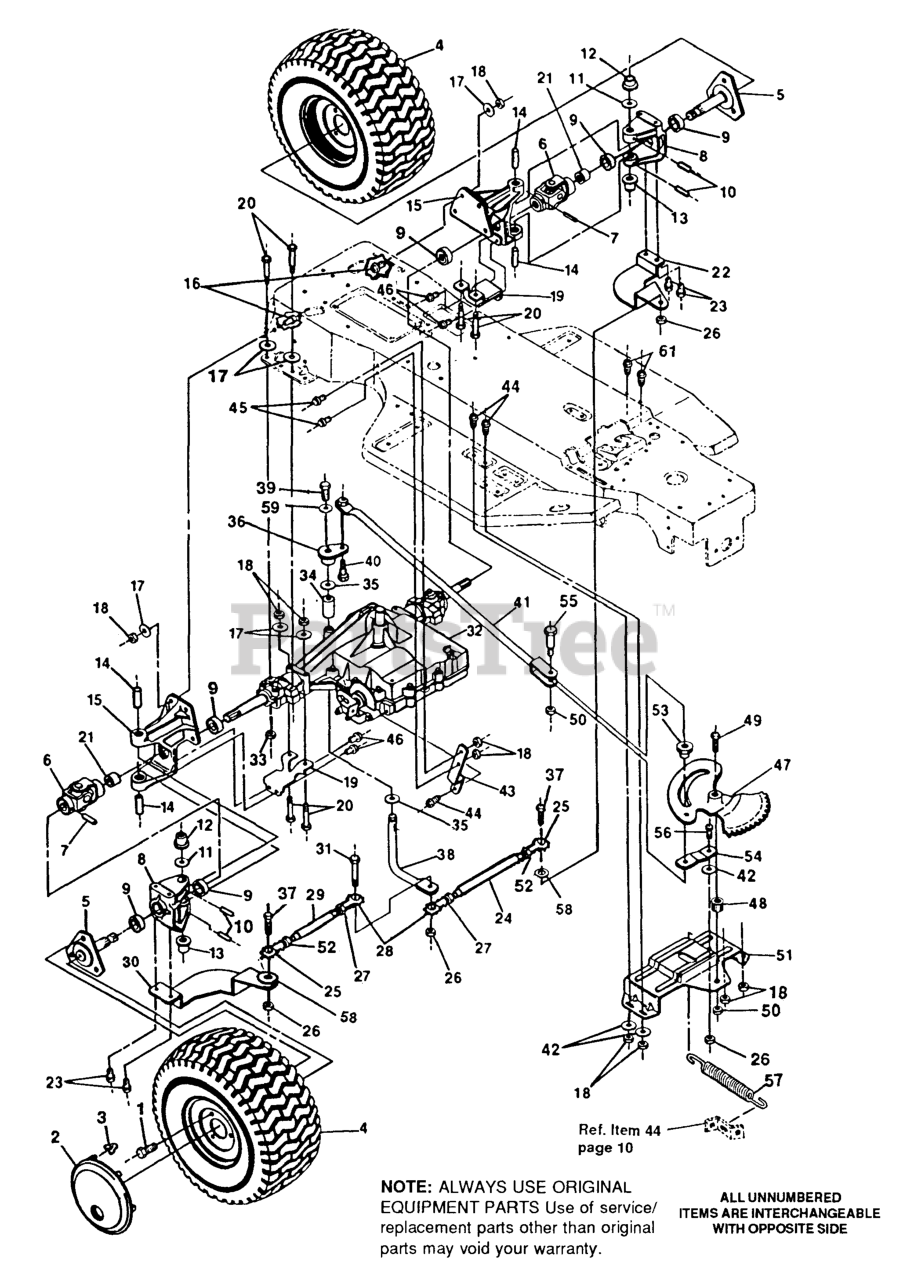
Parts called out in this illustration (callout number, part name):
1	Screw, Hx Hd, 1/2-20 x 1/2 In.
2	Hubcap, 8 In.
3	Clip, Hubcap
4	Wheel & Tire Assembly, Rear
4	Valve Stem
5	Hub Assembly
6	U-Joint Assembly
7	Pin, Grooved, 1/4 x 1-1/2 In.
8	Bracket, Steering Pivot, Outer
9	Bearing
10	Pin, Spring, 1/4 x 1-1/2 In.
11	Washer, Flat
12	Bushing, Shouldered
13	Bushing, Shouldered
14	Pin, Steering Hinge
15	Bracket, Steering Pivot, Inner
16	Screw, Hx Hd, 5/16-18 x 1 In.
17	Washer, Flat, 11/32 In.
18	Nut, Hx, Ctrlk 5/16-18 Thd.
19	Bracket, Transaxle Mounting
20	Screw, Hx Hd, 5/16-18 x 2-1/4 In.
22	Arm, Rear Wheel Steer, L. H.
23	Screw, Self-Tap, 3/8-16 x 3/4 In.
24	Tie Rod, L.H.
25	Tie Rod End, L.H.
26	Nut, Hex, Ctrlk, 3/8-24 Thd.
27	Nut, Hex, Jam, 3/8-24 Thd.
29	Tie Rod End, R.H.
30	Arm, Rear Wheel Steer, R.H.
31	Screw, Hx Hd, 3/8-24 x 1-3/4 In.
32	Contact nearest dealer
33	Nut, Hx, Wd Fl, Lk 5/16-18 Thd.
35	Washer, Flat, 49/64 In.
36	Steering Pivot
37	Screw, Hx Hd, 3/8-24 x 1-1/4 In.
38	Shaft, Steering Pivot
39	Screw, 5/16-24 x 1 In.
40	Bolt, Shoulder, 3/8-24 Thd.
41	Rod Assembly, Rear Wheel Steer
42	Washer, Flat, 3/8 In.
43	Bracket, Transaxle Stabilizer
44	Screw, Hx Hd, Self-Tap, 5/16-18 x 3/4 In.
45	Screw, Hx Hd, 5/16-18 x 5/8 In.
46	Screw, Hx Hd, Self-Tap, 5/16-18 x 5/8 In.
47	Assembly, Sector Gear
48	Bushing, Sector Gear
49	Screw, Hx Hd, 1/2-20 x 2-3/8 In.
50	Nut, Hx, Ctrlk, 1/2-20 Thd.
51	Plate, 4-Wheel Steer Pivot
52	Nut, Jam, 3/8-24 Thd.
53	Cam Yoke Roller
54	Arm, Roller Swing
55	Shoulder Bolt, Cam Roller
56	Shoulder Bolt, Cam Follower Arm Pivot
57	Spring, Clutch/Brake Pedal Return
58	Washer, Split Lock
59	Washer, Flat
60	Woodruff Key, #606
61	Screw, Tap. 5/16-18 x 1/2 In.
